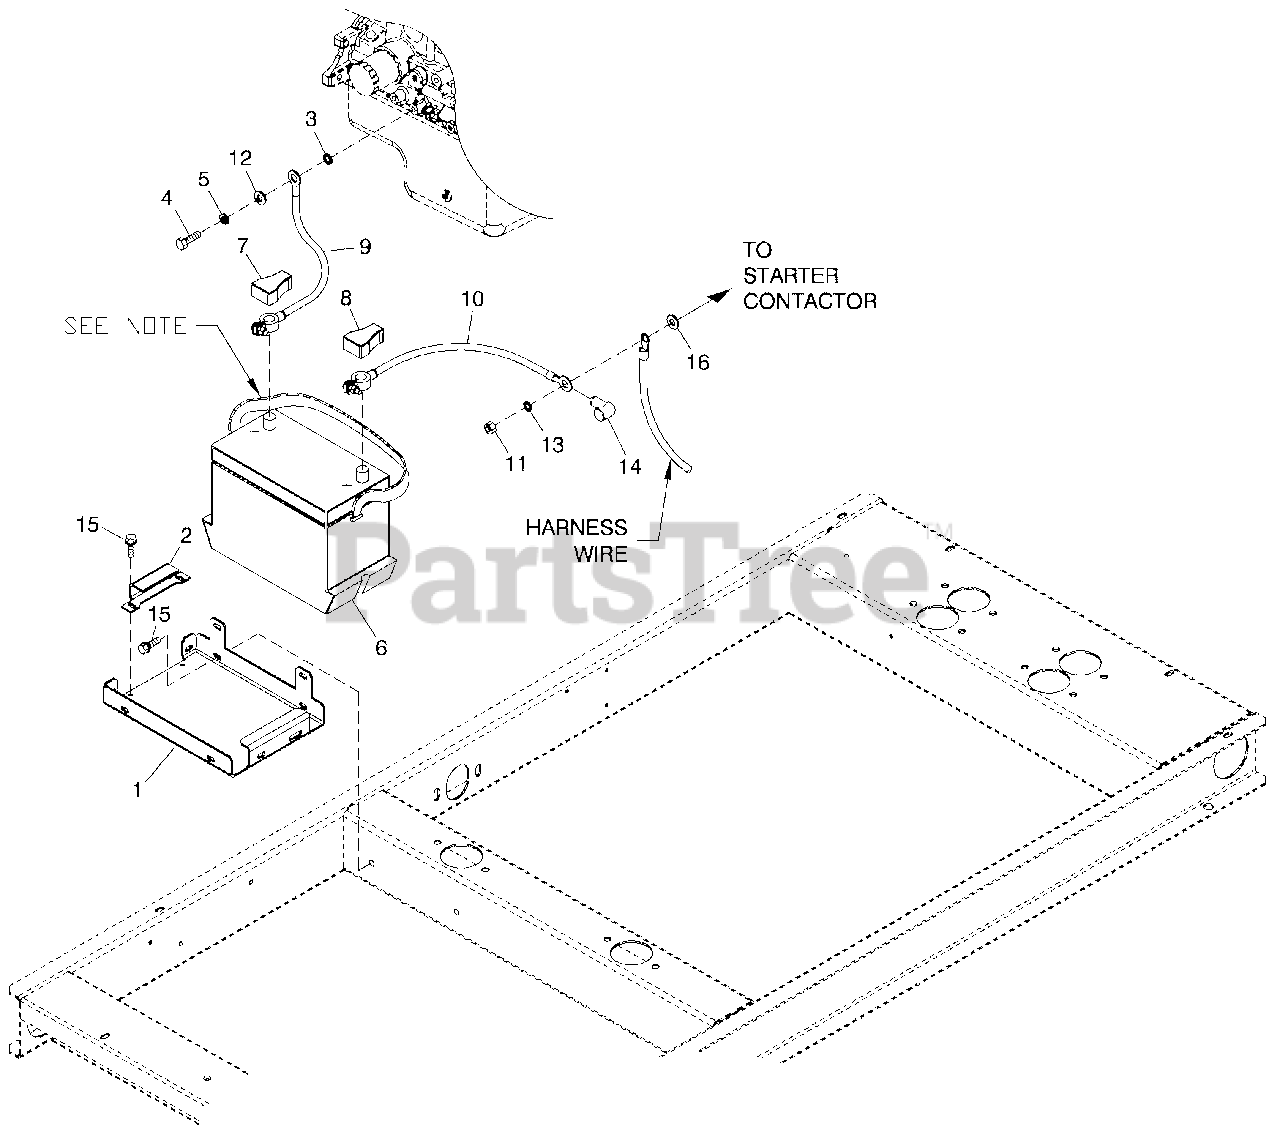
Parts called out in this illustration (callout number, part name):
1	BATTERY TRAY, C1&C2
2	STRAP BATTERY RETAINMENT
3	WASHER SHAKEPROOF EXT 7/16 STL
4	SCREW HHC M10-1.5 X 25 G10.9
5	WASHER LOCK M10
6	BATTERY 12VDC 75-AH 26
7	BATTERY POST COVER RED +
8	BATTERY POST COVER B LK -
9	CAB LE BATTERY B LACK #1 X 30.00
10	CAB LE BATTERY RED #1 X 21.00
11	NUTHEXM8-1.25 G8 YE L CHR
12	WASHER FLAT 3/8-M10 ZINC
13	WASHER SHAKEPROOF EXT 5/16 STL
14	BOOT CONTACTOR CAB LES
15	SCREW THF M6-1 X 16 N WA Z/JS
16	WASHER FLAT 5/16-M8 ZINC
